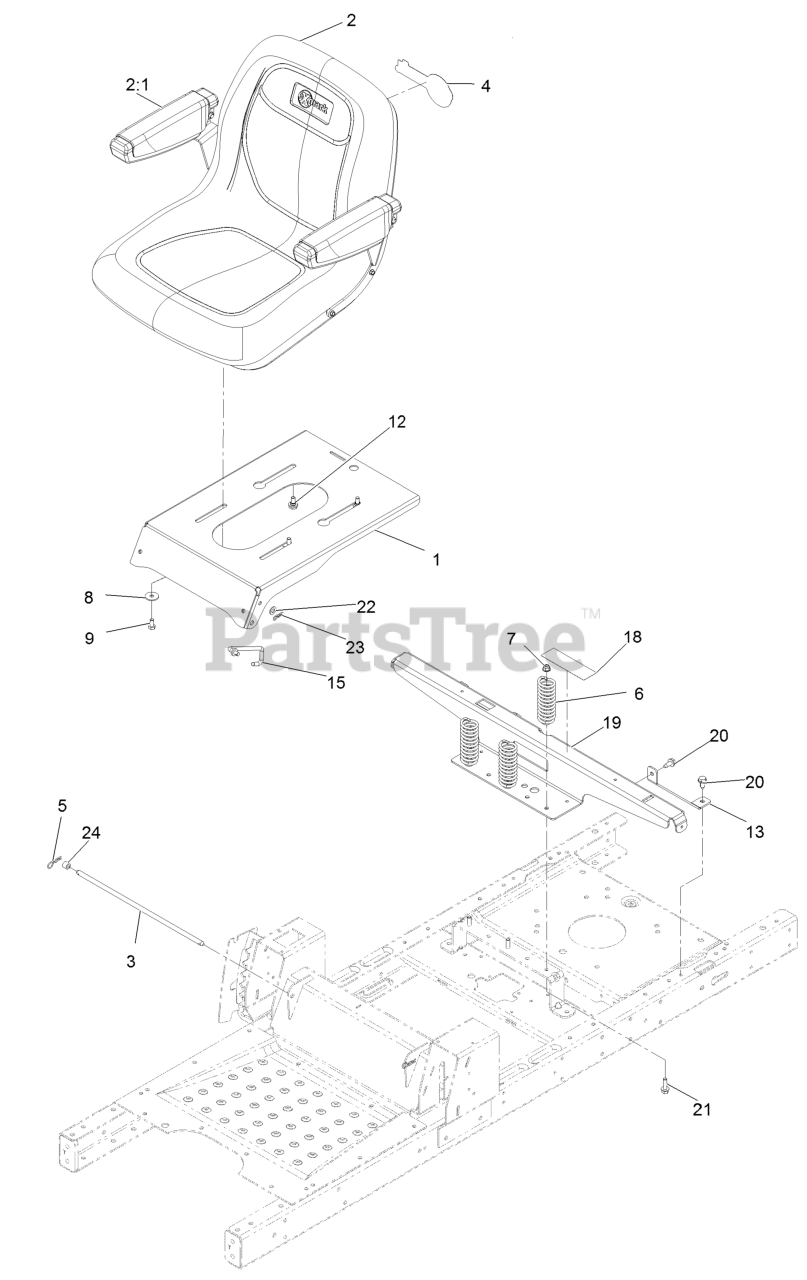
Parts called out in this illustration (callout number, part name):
2	SEAT-18 IN W/ARM
2:1	ARMREST KIT (MILSCO)
3	ROD-STOP
5	PIN-COTTER
6	SPRING-COMPRESSION
7	NUT-HF, NI
8	WASHER-PIVOT
9	SCREW-HH
12	BOLT-SHOULDER,HFH
13	SUPPORT-TANK, REAR
15	STOP-SEAT
18	DECAL-SERVICE, CE
19	SUPPORT-POD, WIDE
20	Screw-HWH 5/16-18 X 3/4 Tf
21	SCREW-HHF
22	WASHER-PLAIN
24	BUSHING-LEVER, LIFT
